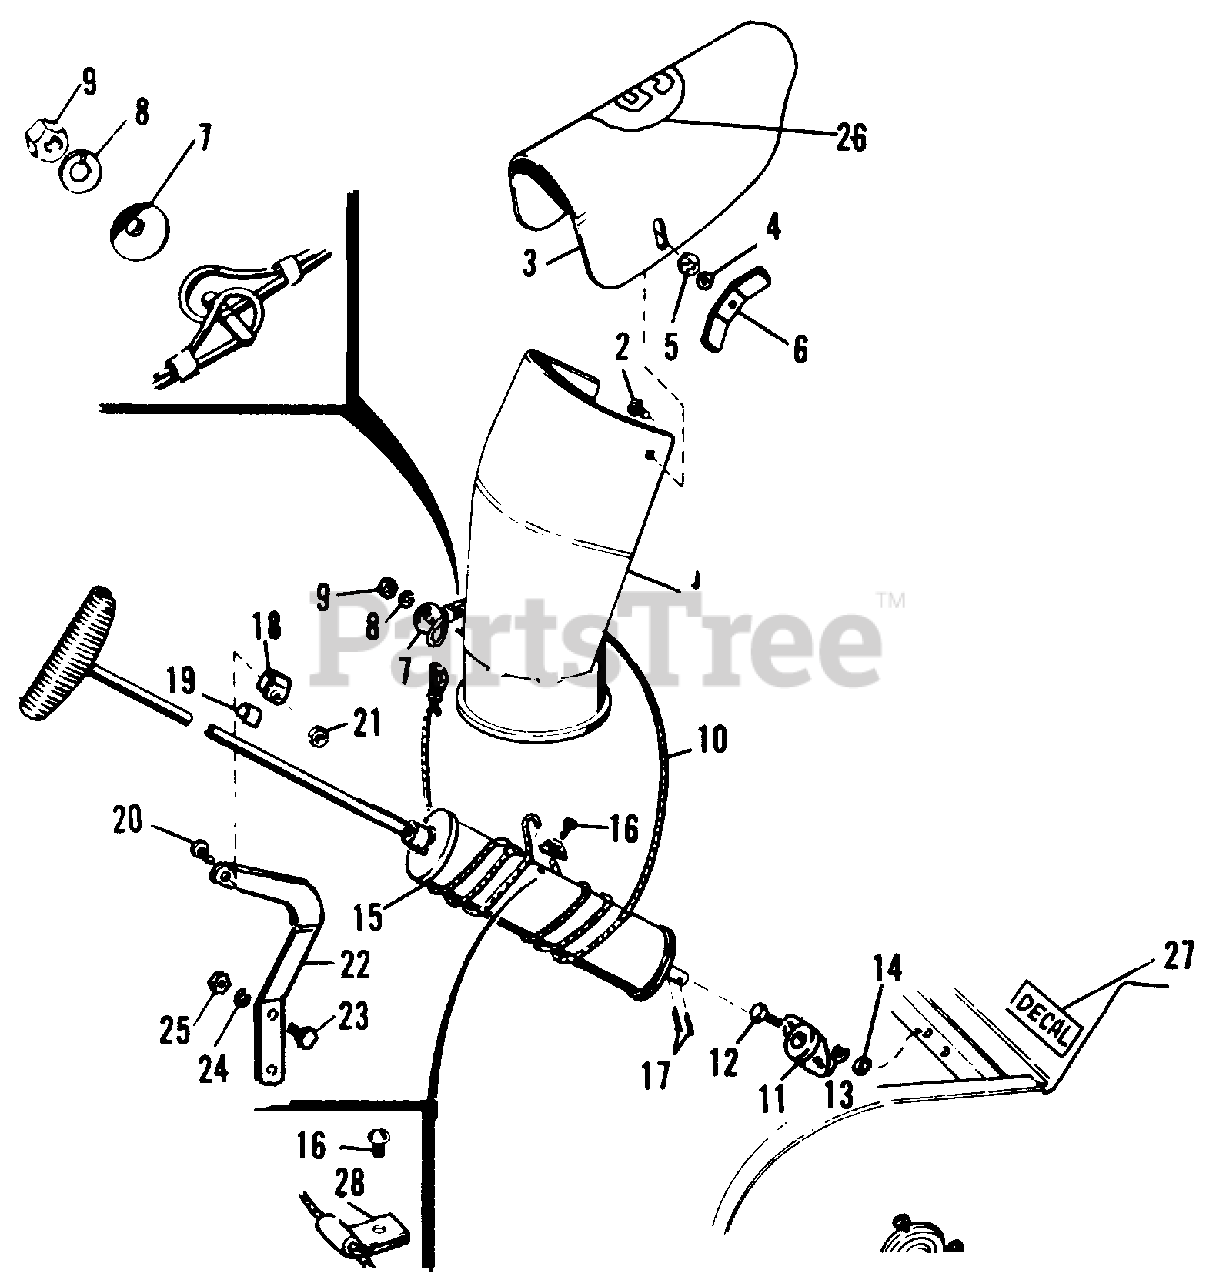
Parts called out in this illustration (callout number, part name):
1	Spout Assembly
2	Carriage Bolt, 5/16"-18 x 3/4"
3	Spout Extension
4	Washer, Plain 3/8"
5	Washer, Lock 3/8"
6	NUT, Wing, 5/16-18
8	Washer, Lock 5/16"
9	Nut, Hex Full 5/16"-18
10	Cable Assembly
12	Capscrew, Hex 1/4"-20 x 5/8"
13	Washer, Lock, 1/4"
14	Full Hex Nut, 1/4"-20
15	Tube Assy. Spout Control
16	Self-tapping Screw, 1/4"-20 x 3/8"
17	Cotter Pin, 1/8" x 3/4"
19	Liner, Guide
20	Capscrew, Hex, 5/16"-18 x 1/2"
21	Nut, Hex, Full, Lock, 5/16"-1
22	Rod Guide Support
23	Hex Capscrew, 3/8"-16 x 1" lg.
24	Lock Washer, 3/8"
25	Hex Nut, Full, 3/8"-16
28	Clamp (For Service Only)
29	Handle Assembly
30	Pin, Cotter
